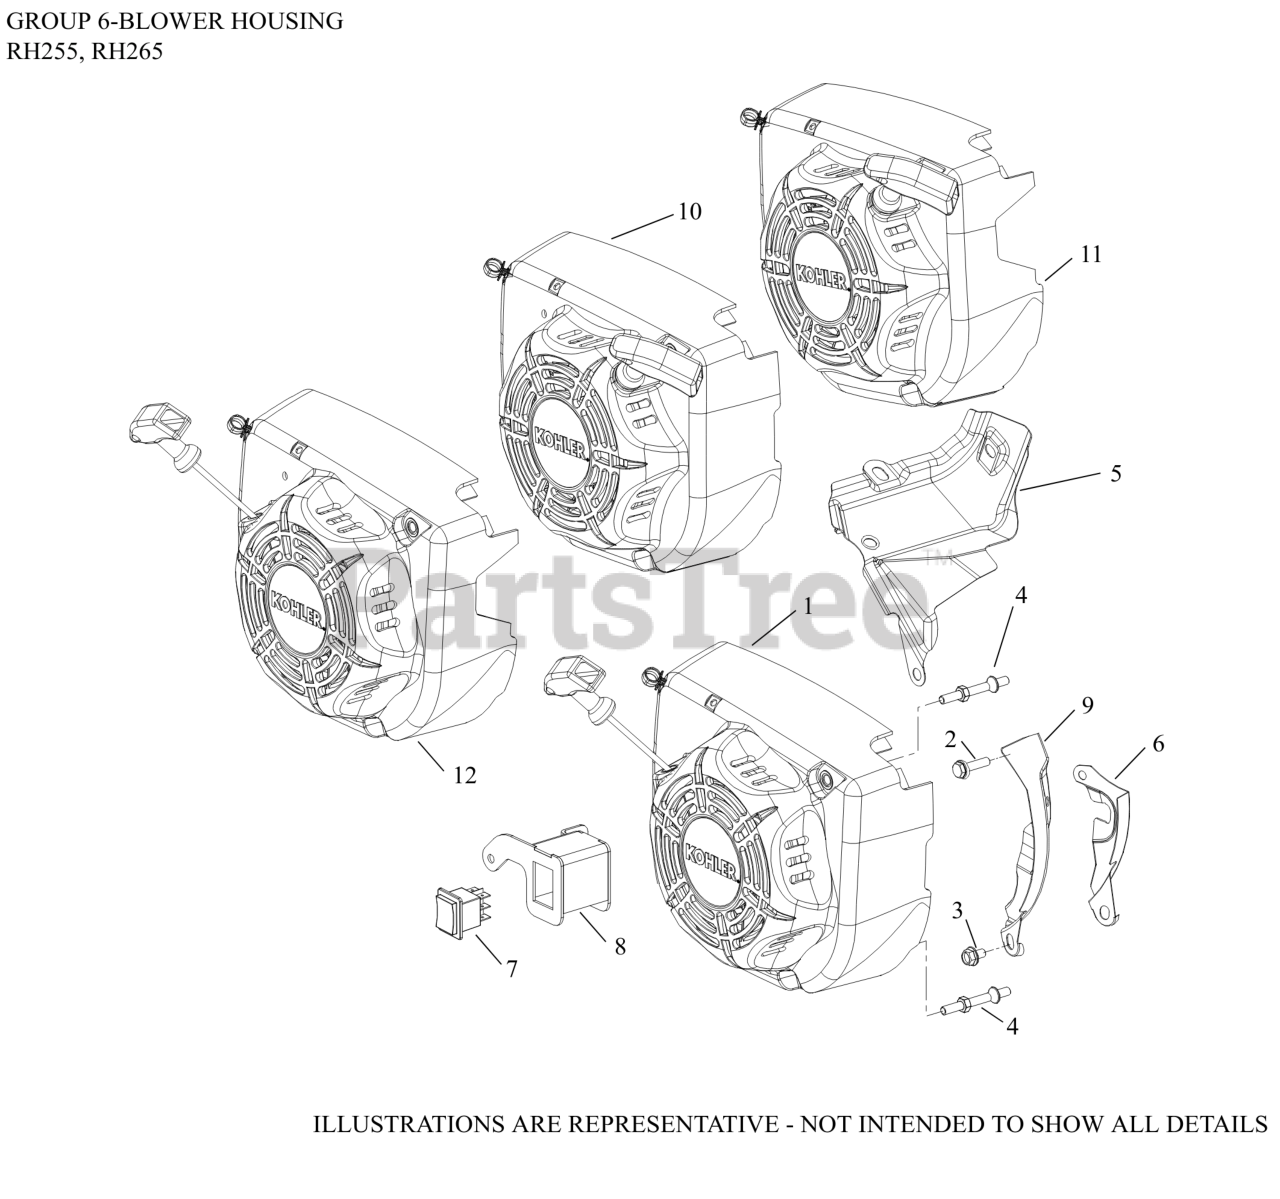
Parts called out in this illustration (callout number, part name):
1	KIT, HOUSING BLOWER RECOIL ASSY
3	SCREW, HEX FLANGE (M6)
4	STUD, BLOWER HOUSING MOUNTING
9	SHIELD, FLYWHEEL
